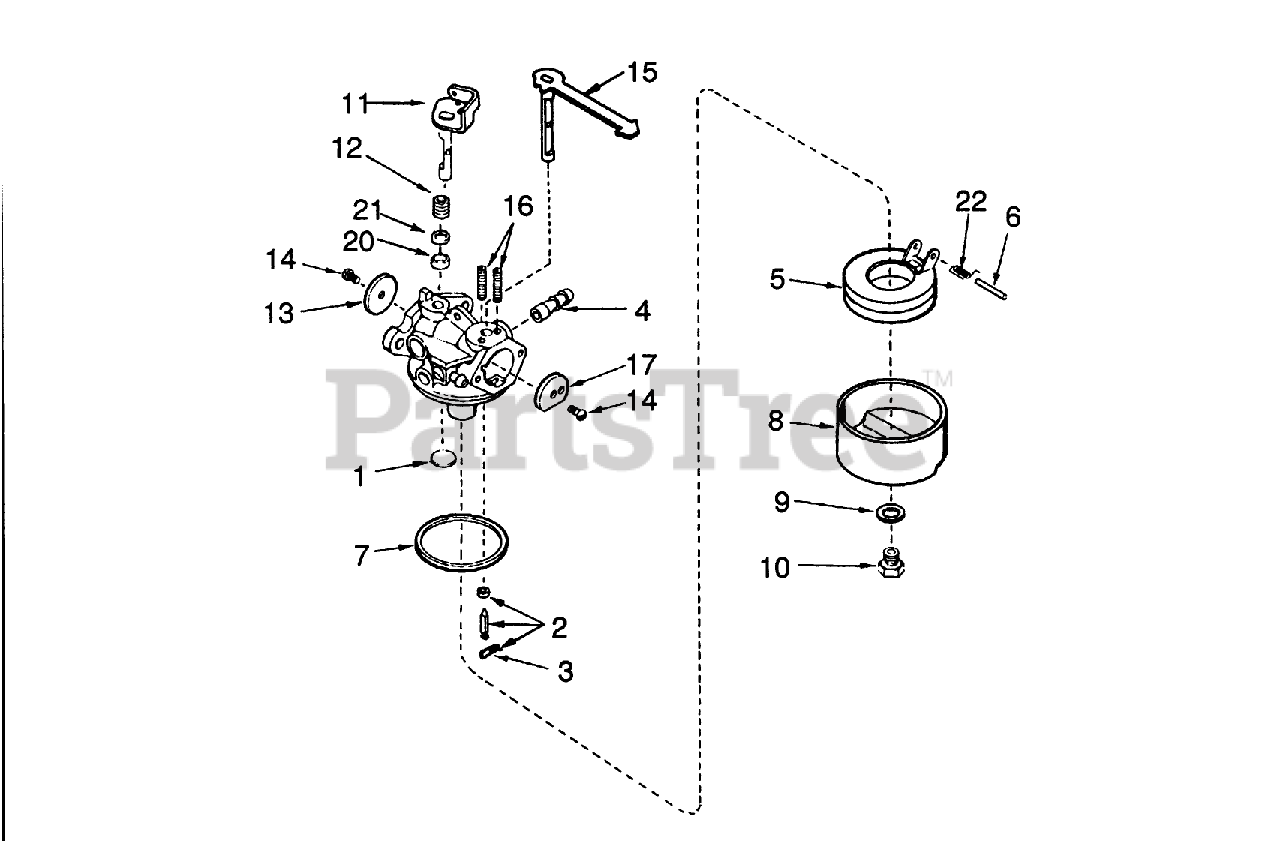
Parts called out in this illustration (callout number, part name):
1	Plug-Welch, Atmospheric Vent
2	Inlet Needle, Seat Clip Assy. (Incl. No. 13)
3	Clip-Spring
4	Fitting-Fuel
5	Float
6	Shaft-Float
7	O Ring-Bowl, Float
8	Bowl Float
9	Gasket-Bowl
10	Nut-Float Bowl
11	Shaft/Lever-Throttle
12	Spring-Trottle, Return
13	Shutter-Throttle
14	Screw-Shutter
15	Choke Shaft Lever Assy.
16	Spring-Positioning, Choke
17	Shutter-choke
20	Seal-Dust
21	Washer-Seal, Dust
22	Spring-Float, Dampening
